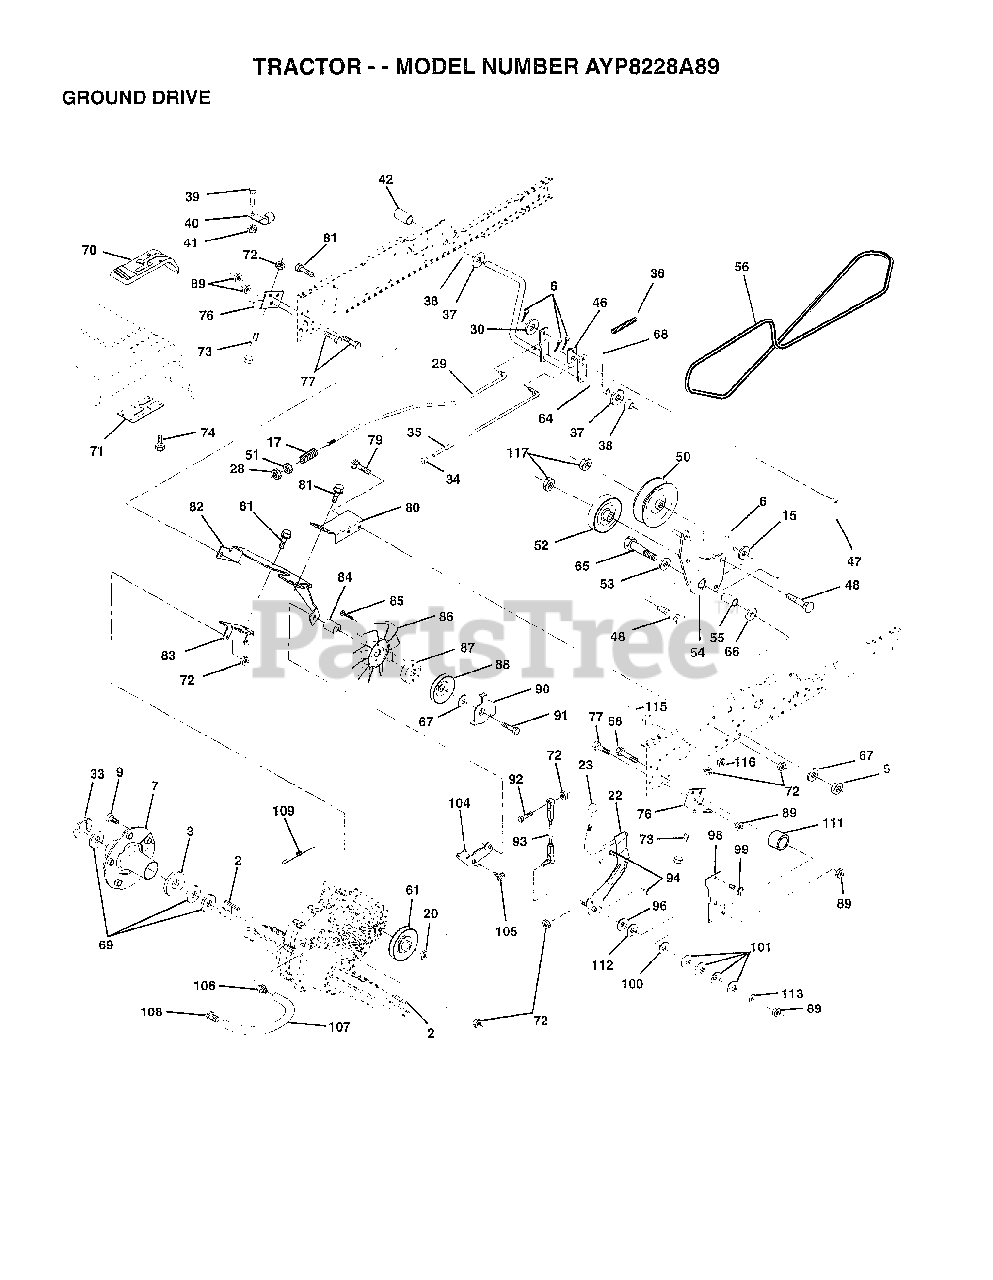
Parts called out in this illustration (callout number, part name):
2	KEY 1/4 X 2.5
3	WASHER T
6	COTTER PIN
7	HUB WHEEL ASM
9	BOLT.HUB.WHL.REAR
15	WASHER
17	SPRING ROD BRAKE
22	ARM ASM SHIFT
23	KNOB.DUCKHEAD.1/2
28	NUT
29	ROD BRAKE
30	WASHER HYT
33	E RING HYT
35	ROD BRAKE PART GT
36	SPRING.GRND.DRIVE
37	WASHER
38	BUSHING.NYLINER
39	SCREW
40	ACT-SWITCH T
42	PEDAL COVER T
46	RETAINER.SPRING
47	ROD.CLUTCH
48	BOLT.3/8-16X1.50
50	FLAT IDLER PULLEY
52	PULLEY.IDLER.V.GR
53	WASHER T
54	CLUTCH.ARM.ASM
55	"LY, BEARING"
56	BELT-V 84.5
58	BOLT
61	PULLEY TRANSAXLE
64	SHAFT-BRAKE/CLUTC
65	AXLE BOLT
66	WASHER.HARD.BLADE
67	WASHER
68	ROLL PIN STD
69	WASHER
71	"PLATE CONSOLE,SFT"
73	BOLT.HEX.FLGHD.
74	SCREW HEXWSH H-L
76	BRACKET TRAN VGTH
77	BOLT
79	BOLT
80	BRACKET TORQUE RH
81	SCREW
82	BRACKET.MTG.FAN
83	STRAP TORQUE MID
84	SPACER
85	SCREW YTV
86	"FAN 7"" HYDRO"
87	ADAPTER FAN
88	PULLEY FAN
89	NUT GTV
90	KEEPER BELT
91	SCREW.HXWSH.3/8
93	LINK ASM SHIFT
94	XMAS TREE FASTNER
96	WASHER NICKEL PLT
98	BRACKET SHIFT
99	SCREW LT
100	WASHER COMPRESSIN
101	WASHER-BELLVILLE
104	BRACKET IDLER
105	SCREW CRT
106	O-RING.ASM.70110
107	"LINE FUEL,HYD 15"""
108	CAP.VENT.70109
109	SPRING BRAKE
111	"SPACER-LEVER,SHIF"
112	"WASHER-NYLON,HIGH"
113	NUT
115	"KEEPER,DRIVE BELT"
116	"NUT HEX,LOCK,FLAN"
